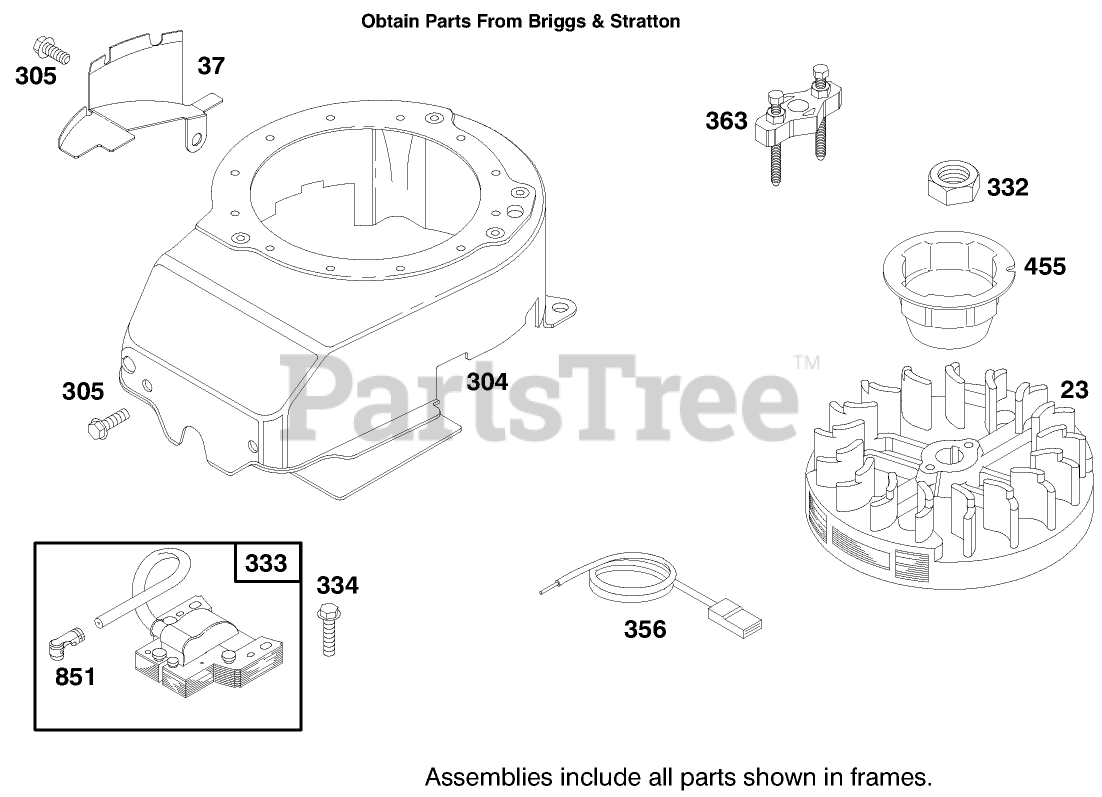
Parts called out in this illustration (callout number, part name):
23	Flywheel
37	Flywheel Guard
304	Housing-Blower
305	Screw-Hex
333	Armature-Magneto
334	Screw-Sem
356	Wire Stop
363	Puller-Flywheel
851	Terminal-Spark Plug
